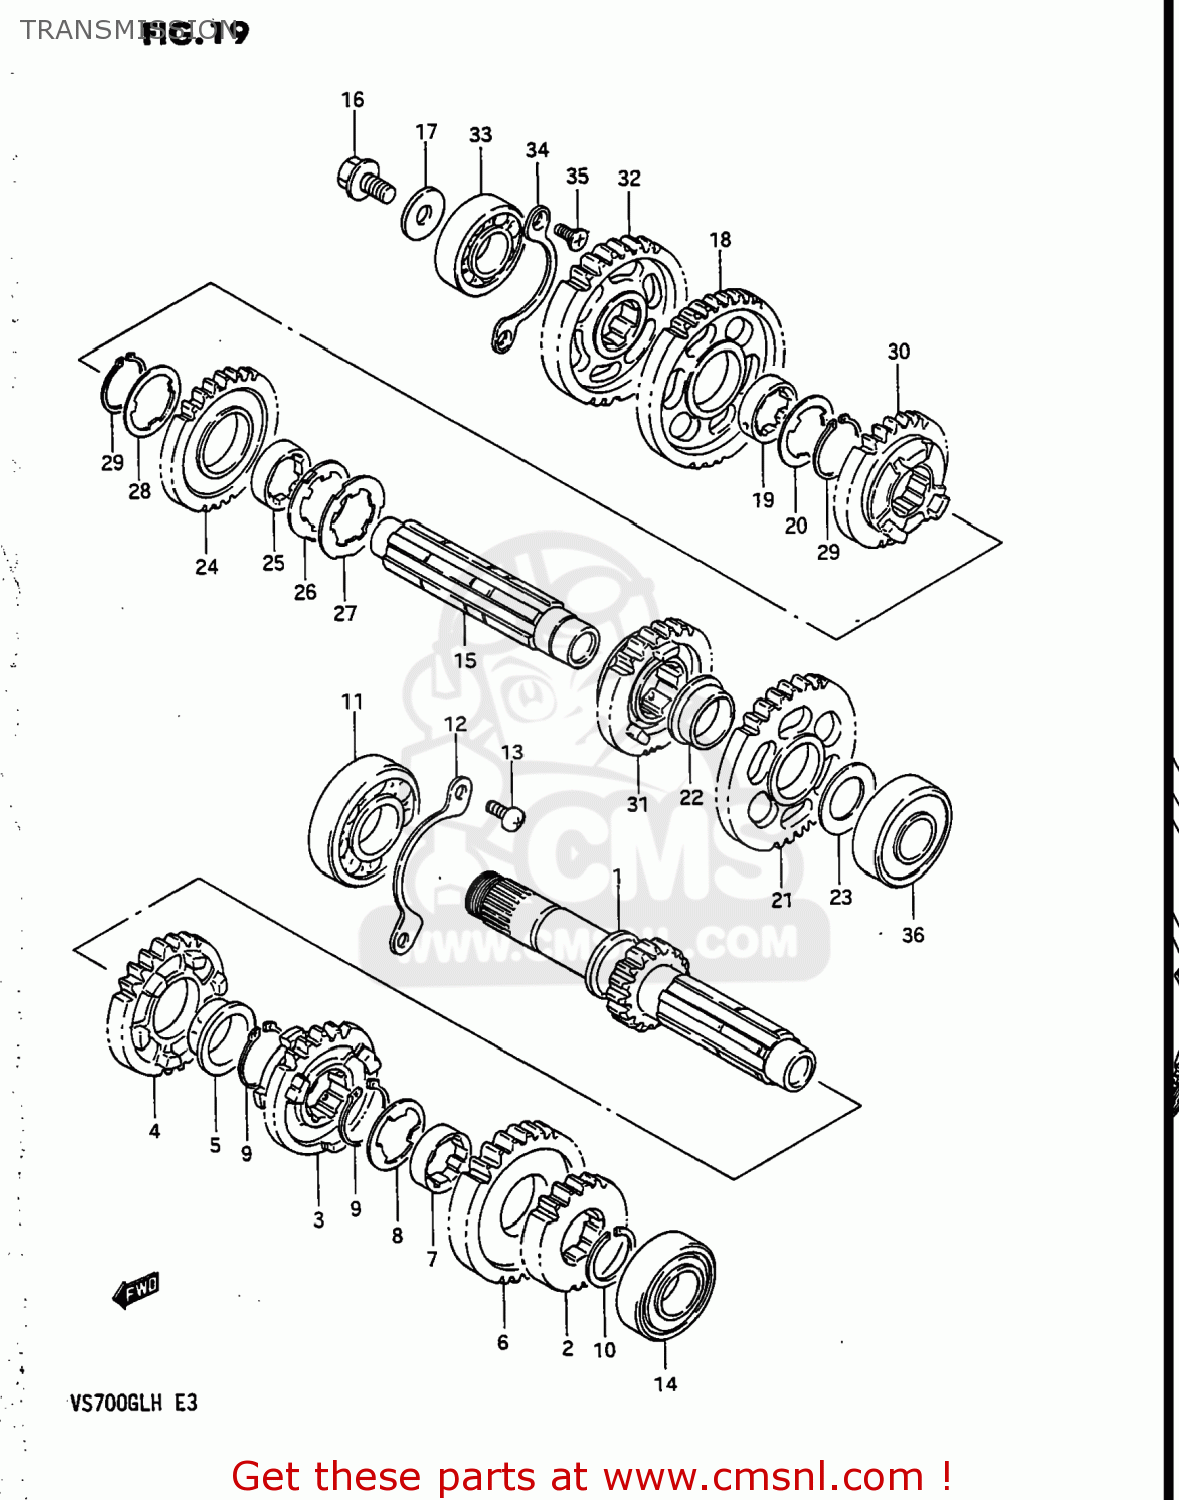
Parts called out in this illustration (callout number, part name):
1	COUNTER SHAFT
2	GEAR,2ND DRIVE(NT:19)
3	GEAR,THIRD DRIVE
4	GEAR,4TH DRIVE(NT:25)
5	BUSHING
6	GEAR,FIFTH DRIVE (NT:27)
7	BUSHING
8	WASHER,LOCK
9	RING,SNAP
10	CIRCLIP
11	BEARING(25X62X17)
12	RETAINER,CNTR SHAFT BEARING
13	SCREW
14	BEARING 20X47X14
15	SHAFT,DRIVE
16	NOZZLE,DRIVE SHAFT
17	WASHER
18	GEAR,FIRST DRIVEN (NT:32)
19	BUSH
20	WASHER,LOCK
21	GEAR,2ND DRIVEN(NT:31)
22	BUSH
23	WASHER
24	GEAR,THIRD DRIVEN
25	BUSH
26	WASHER
27	WASHER,LOCK
28	WASHER,LOCK
29	CIRCLIP
30	GEAR,FOURTH DRIVEN
31	GEAR,FIFTH DRIVEN
32	GEAR,REDUCTION DRIVE(NT:30)
33	BEARING(20X52X15)
34	RETAINER,DRIVE SHAFT BEARING
35	SCREW
36	BEARING(20X52X15)
